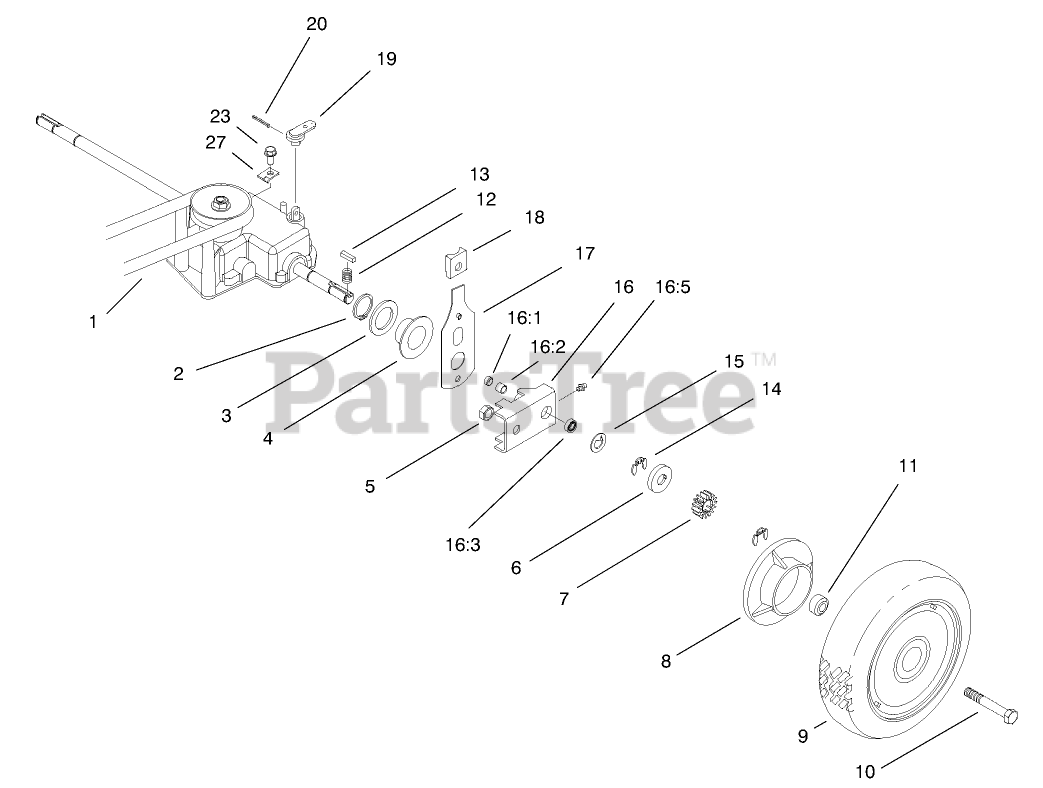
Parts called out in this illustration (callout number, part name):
1	V-BELT
2	RING-RETAINING
3	WASHER
4	CAP-END
5	NUT-LOCK, CONE
6	WASHER-THRUST, OUTER
7	GEAR-PINION
8	COVER-WHEEL
10	SCREW-HH
11	SPACER-COVER, WHEEL
12	SPRING-COMPRESSION
14	RING-RETAINING
15	WASHER-THRUST, OUTER
16	PIVOT ARM ASM
16:1	SEAL-OIL
16:3	BEARING-WHEEL
17	REAR SPRING ARM ASM
18	KNOB-ARM
19	LEVER-SHIFT
20	PIN-SPRING
23	SCREW-HWHTF
27	CLAMP-CABLE
